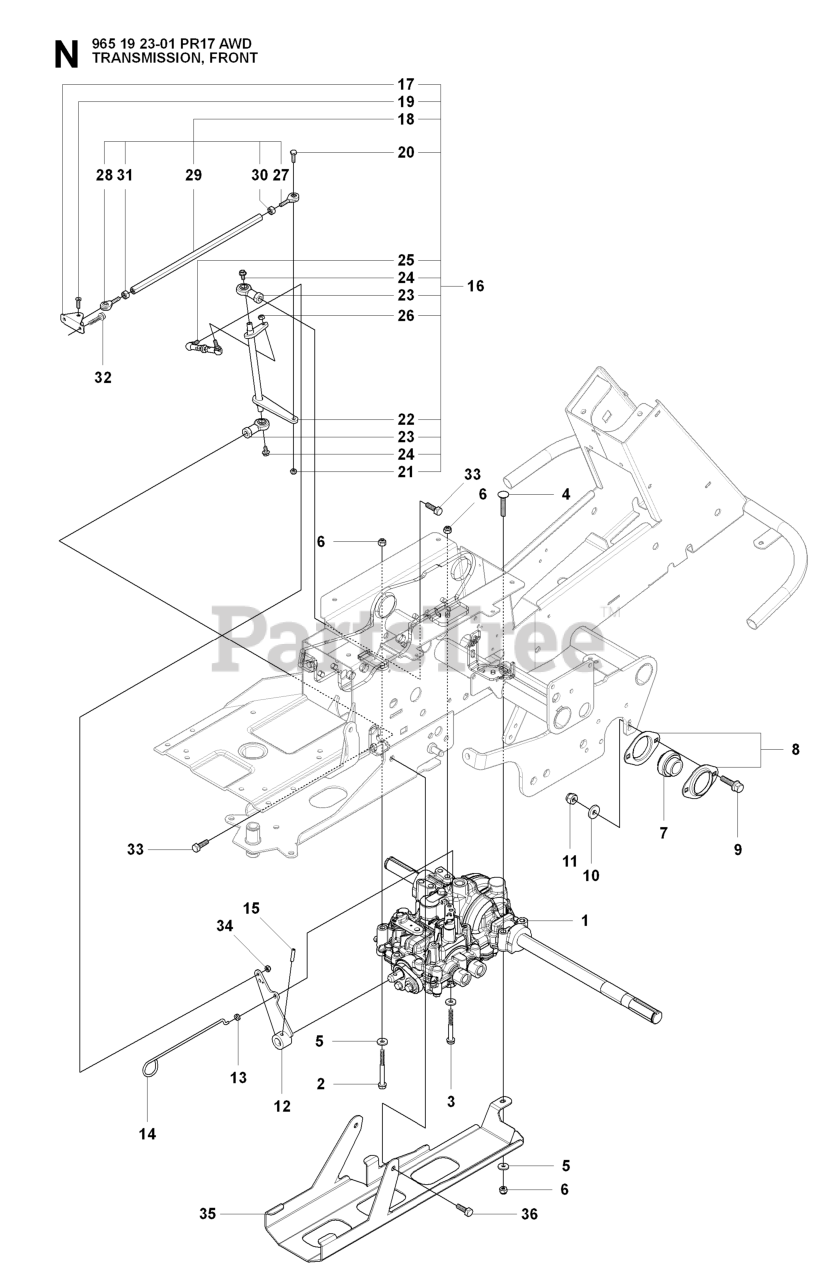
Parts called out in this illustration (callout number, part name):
5	WASHER BRB 8.4X17
6	LOCKNUT M8
8	BEARING HOUSING
9	BOLT
10	WASHER BRB 8.4X17
11	LOCKNUT M8
13	FUEL TANK BUSHING
18	ROD
21	NUT FLANGE - M6
24	SCREW EHHFM
25	ADJUSTING ROD
26	NUT FLANGE - M6
33	Screw M10x25
34	LOCKNUT M6
